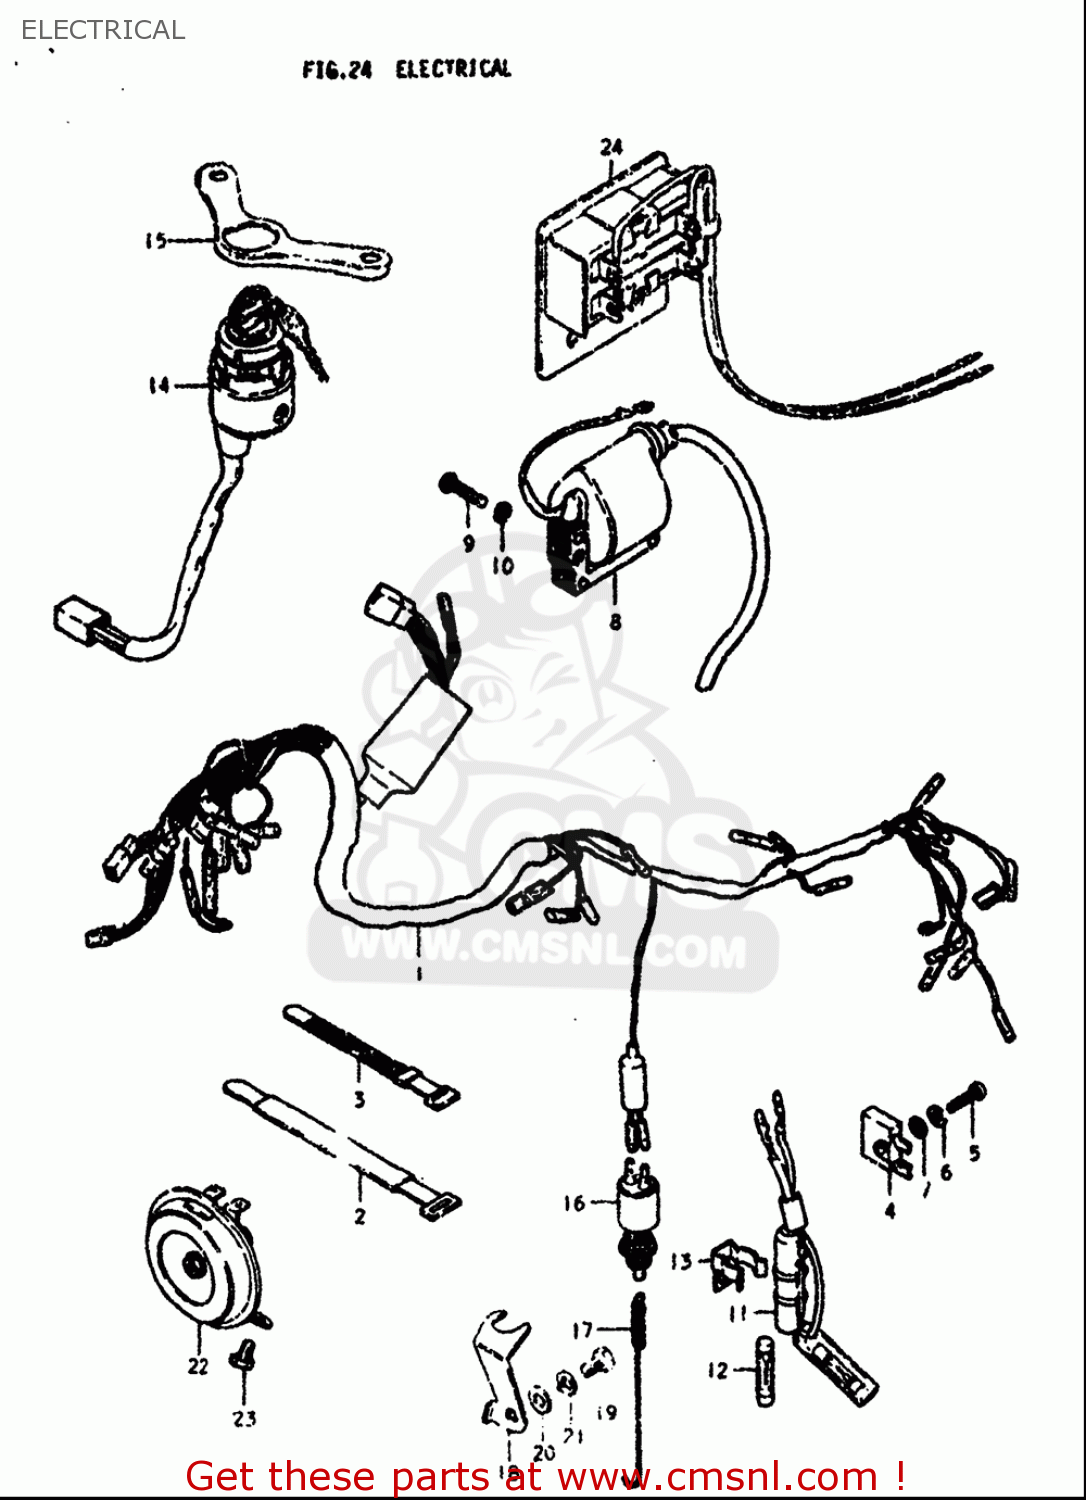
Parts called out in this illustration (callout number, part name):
2	CLAMP
3	CLAMP(L:120)
4	RECTIFIER ASSY
5	SCREW
6	WASHER,LOCK
7	WASHER
8	COIL ASSY,IGNITION
9	SCREW
10	WASHER,LOCK
11	CASE ASSY,FUSE
12	FUSE(15A)
14	SWITCH ASSY,IGNITION
16	SWITCH ASSY,BRAKE LAMP
17	SPRING
18	BRACKET,STOP LAMP SWITCH
19	BOLT
20	WASHER
21	WASHER,LOCK
22	HORN ASSEMBLY
23	BOLT
24	RESISTOR ASSY,MAGNETO
